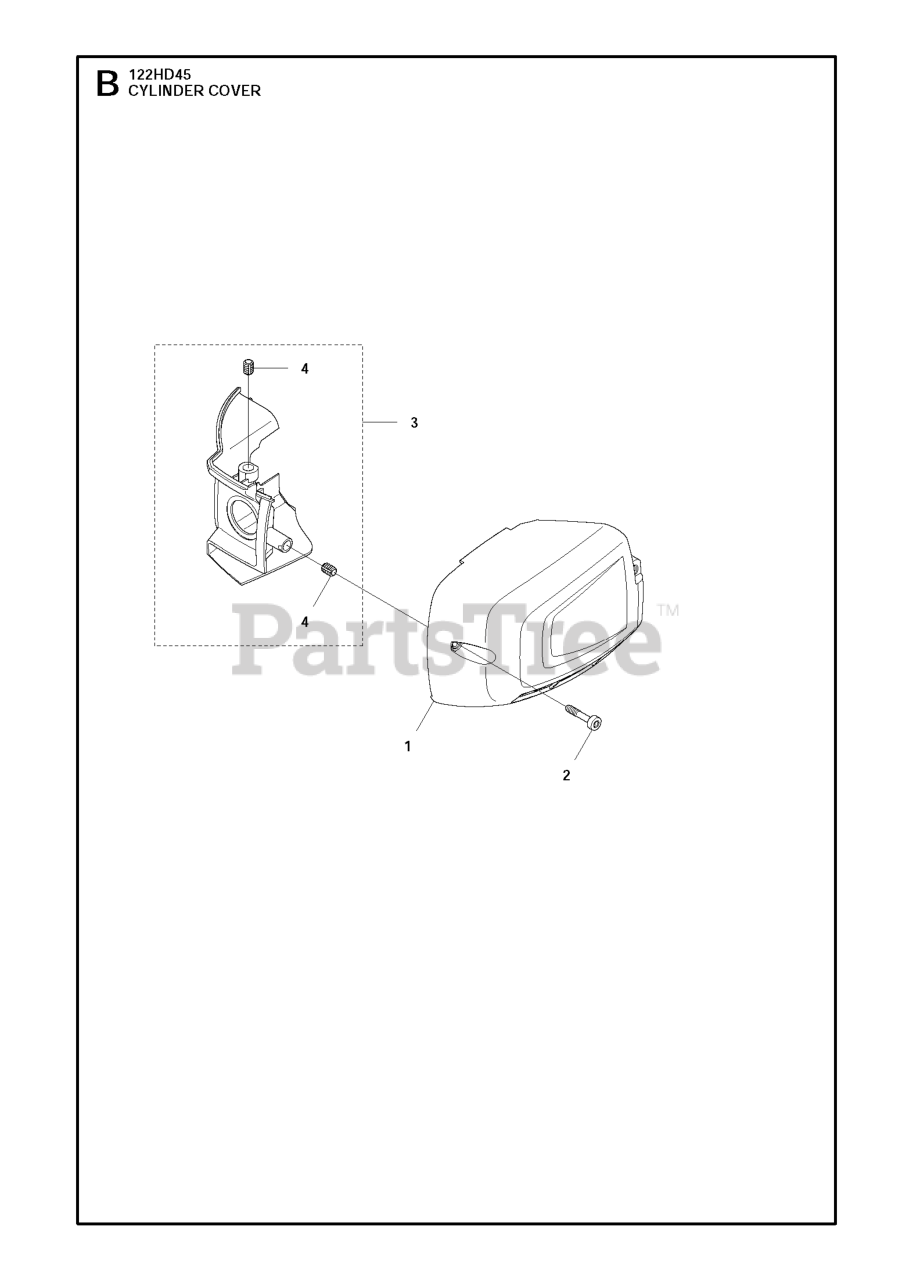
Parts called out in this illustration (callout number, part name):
1	HEAT PROTECTOR
2	SCREW CITXSCMO M5X25
3	SCREW ITXPANTT M5X10 ZPB (A00
3	CYLINDER COVER ASSY
4	THREAD BUSHING
7	CAP.ASSY.FUEL.3".N-EPA.GRY.498
8	BOLT 3/8-16X1-1/8
